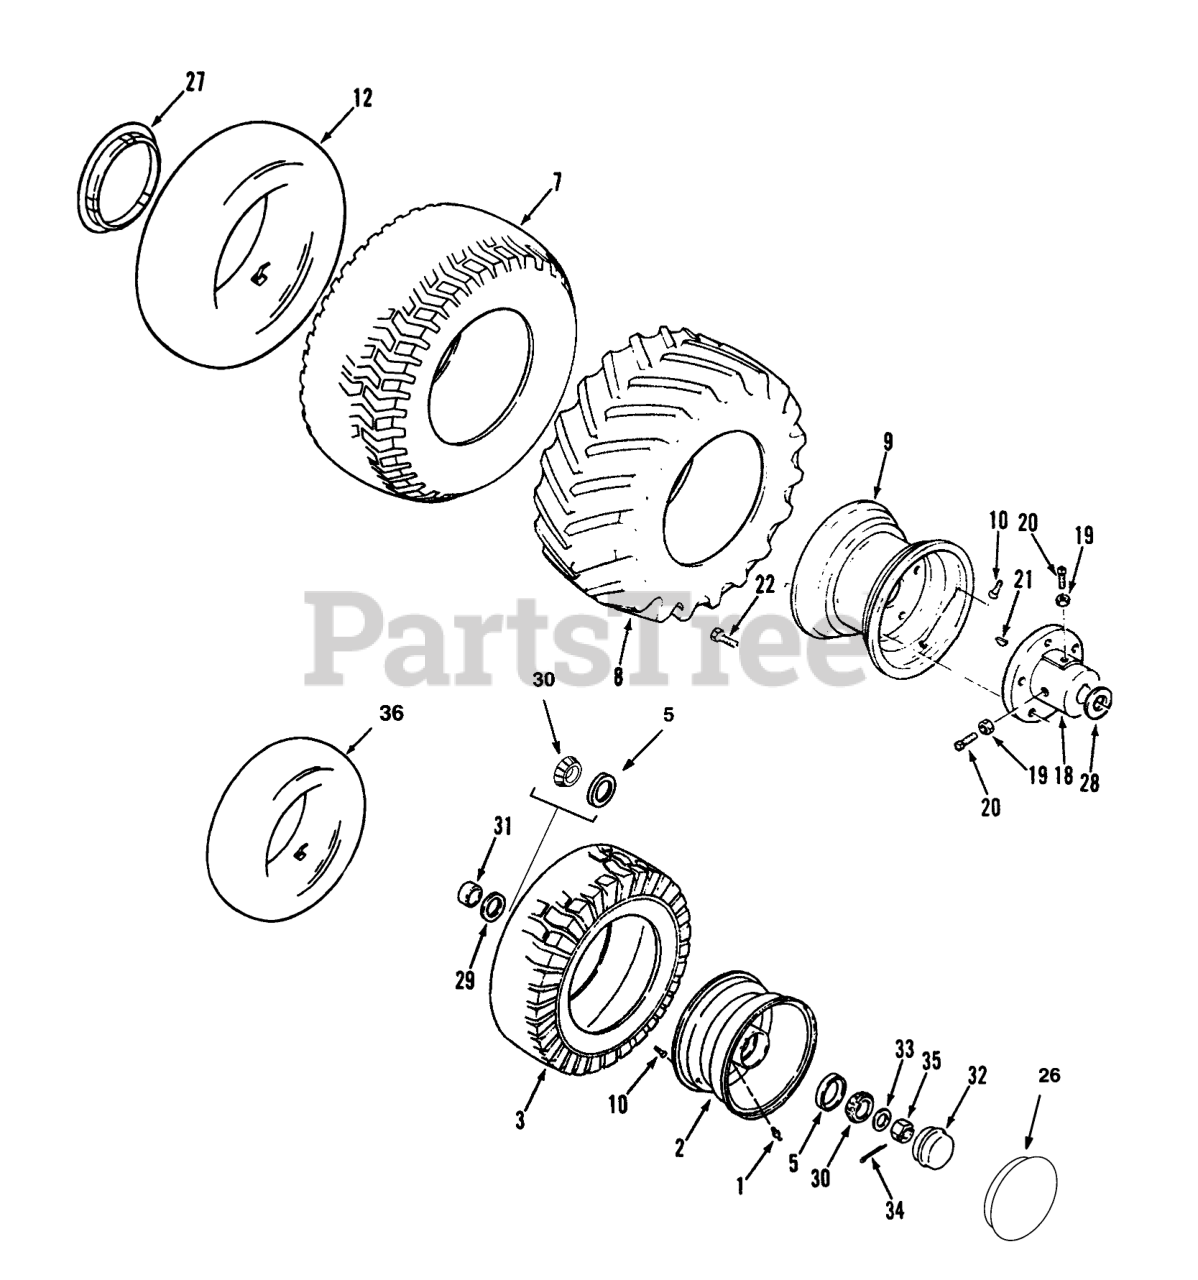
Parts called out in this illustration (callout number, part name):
1	ZERK-GREASE
2	Wheel-Front (Includes Item 1 & Qty. 2 of Item 5)
3	TIRE-16 X 7.50 TURF
5	Cup
7	TIRE 23 X 10.50-12
8	Tire-Cleat, Rear
9	RIM ASM
10	VALVE
12	Rear Tube
18	Hub Rear
19	NUT-JAM
20	SCREW-SET, SQH
21	KEY-WOODRUFF
22	BOLT-LUG
26	8"-HUB CAP LOGO
27	12"-HUB CAP LOGO
28	WASHER-THRUST
29	Seal
30	Bearing
31	SPACER
32	DUST CAP
33	Washer
34	PIN-COTTER
35	NUT-HEX, SLOTTED
